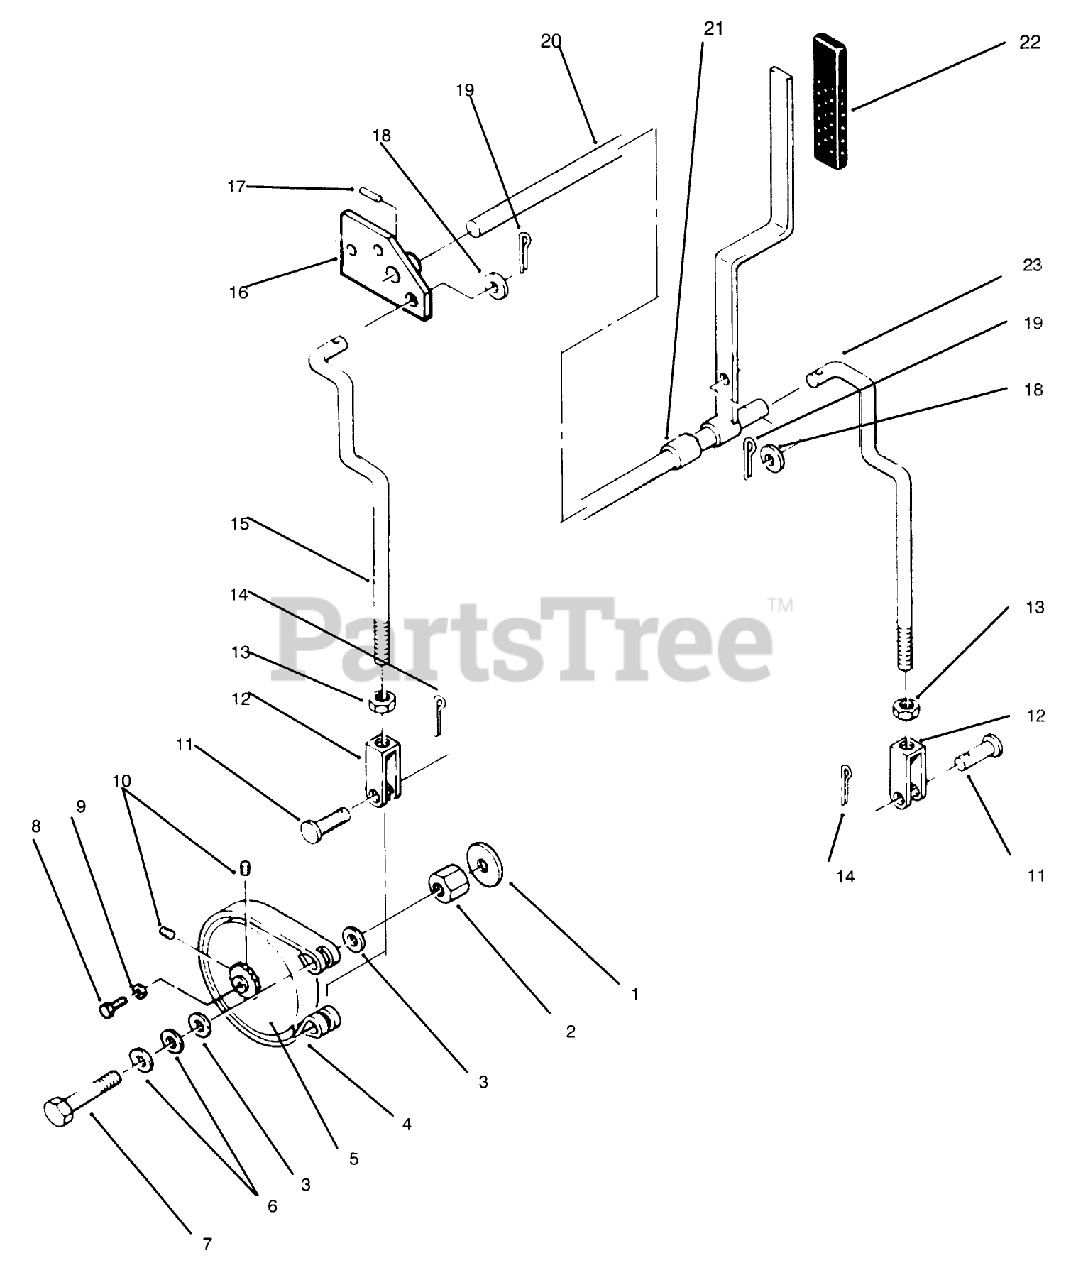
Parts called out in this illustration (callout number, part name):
1	WASHER
2	NUT-COUPLING
3	WASHER-FLAT
4	BRAKE-BAND
5	ASS'Y-DRUM SPROCKET
6	WASHER-SPRING
7	SCREW-HH
8	SCREW-HH
9	WASHER
10	SCREW-HSH
11	PIN-CLEVIS
12	ASSY-YOKE BRAKE
13	NUT-HEX
14	PIN-COTTER
15	ROD-BRAKE R.H.
16	ASSY-PARKING BRK B
17	SPIROL PIN H D
18	WASHER-PLAIN
19	PIN-COTTER
20	ASSY-PARKING BRK
21	SPACER-PARKING BR B
22	GRIP-HANDLE
23	ROD-BRAKE L.H.
